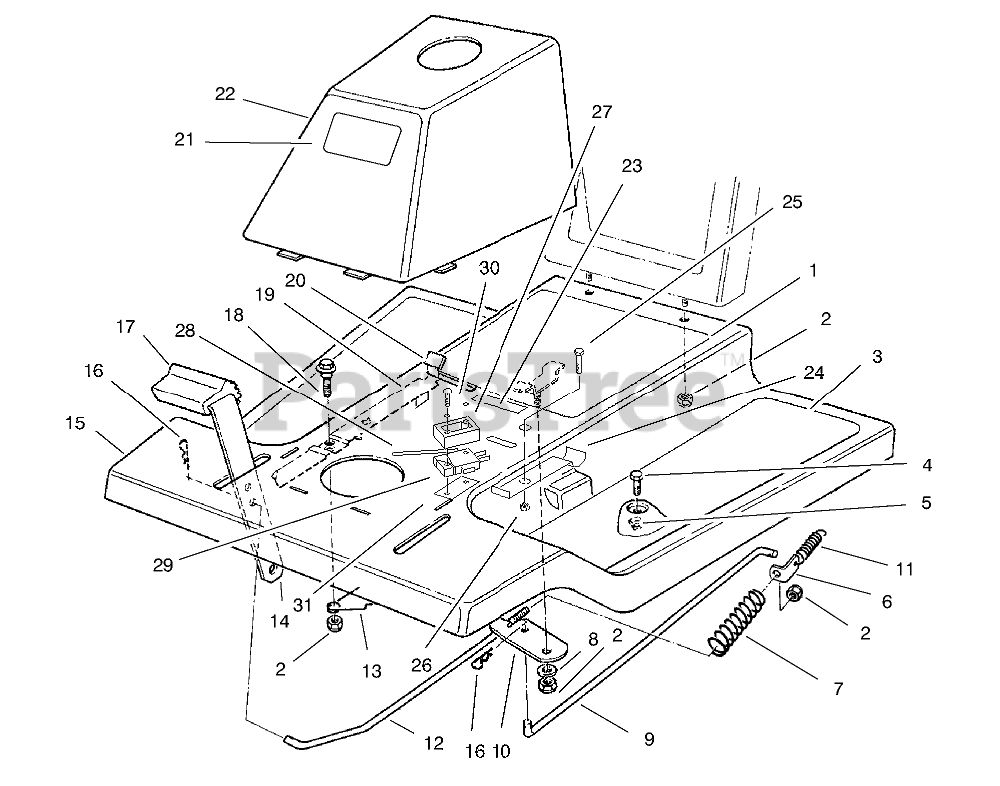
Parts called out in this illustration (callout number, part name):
1	DECAL - INSTRUCTION
2	NUT-LOCK, NI
3	TREAD-FOOT
4	SCREW-HH
5	NUT-TINNERMAN
6	BRACKET-BRAKE RETURN
7	SPRING-TRACTION BRAKE
8	WASHER-PIVOT
9	ROD-TRANS BRAKE
10	LEVER-BRAKE
11	SPRING-IDLER
12	ROD-FRONT BRAKE
13	SPRING-PARKING BRAKE
15	Body W.A.-Front
16	PIN-COTTER
17	PAD-PEDAL
18	SCREW-SHOULDER
19	Lever-Brake, Parking
20	TIP-PARKING BRAKE
21	DECAL
22	Tower (Incl. Ref. #21)
23	DECAL - PARKING BRAKE
24	CLAMP - HARNESS
25	SCREW-HH
26	NUT-LOCK, NI
27	SPACER
28	SWITCH-MICRO
29	PLUNGER-SEAL
30	SCREW-PHL 4-40X1 1/4
31	NUT-SPEED
